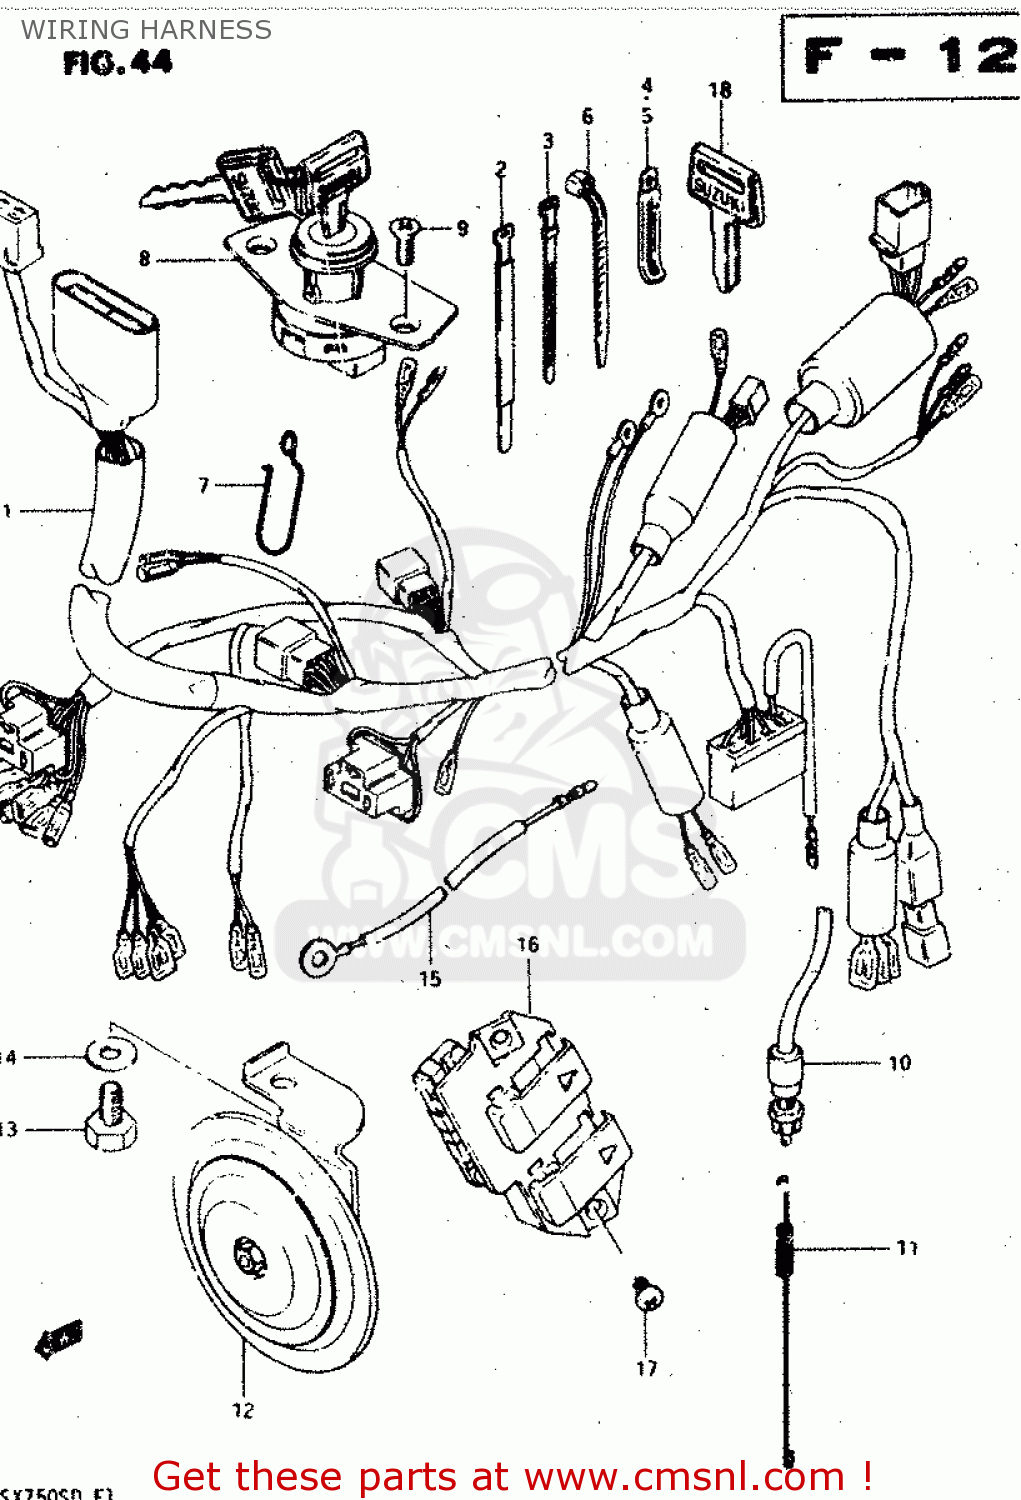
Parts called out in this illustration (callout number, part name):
1	WIRING HARNESS
2	CLAMP
3	CLAMP(L:80)
4	CLAMP
5	CLAMP
6	CLAMP(L:95)
7	BOOT,WIRING HARNESS
8	SWITCH ASSY,IGNITION
9	SCREW
10	SWITCH ASSEMBLY,STOP LAMP
11	SPRING
12	HORN
13	BOLT 8X12
14	WASHER
15	WIRE
16	SWITCH ASSY,SIDE COVER,L
17	SCREW
18	KEY,BLANK
